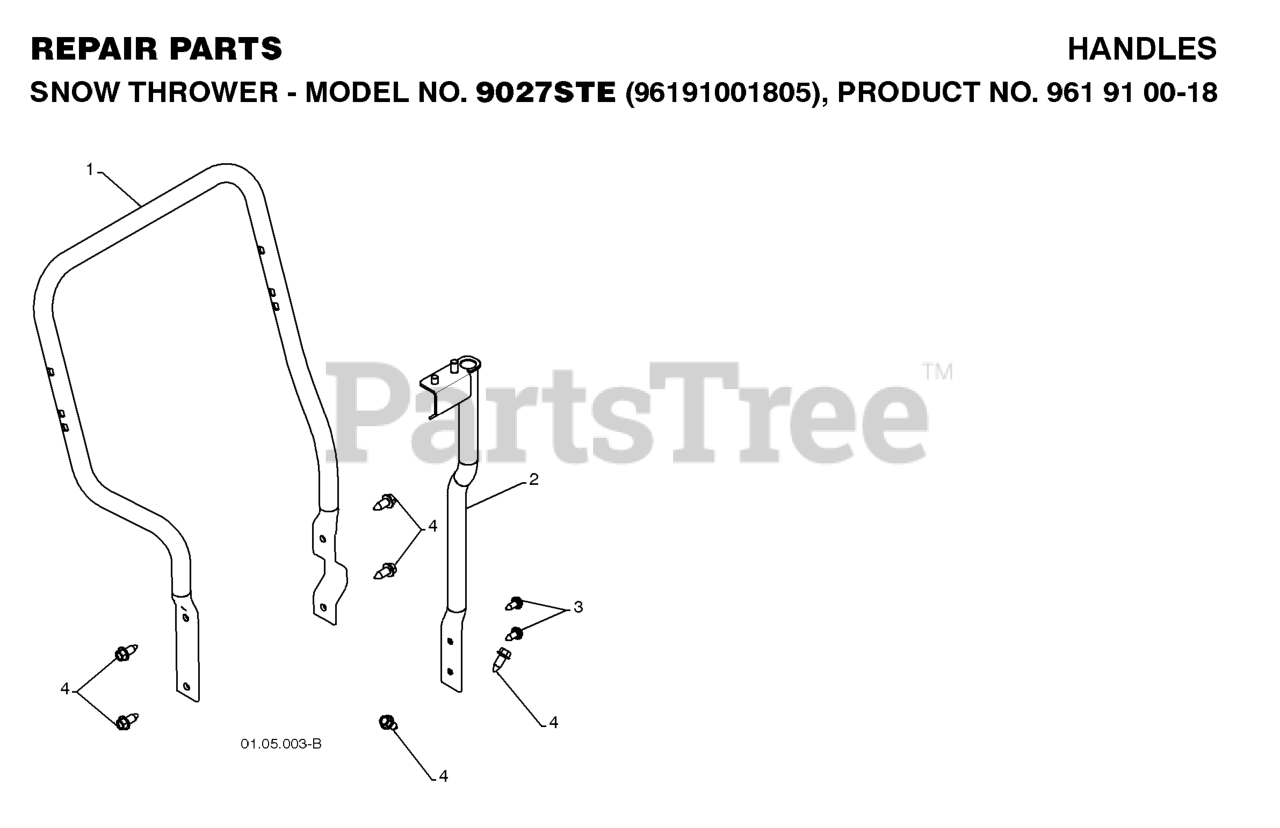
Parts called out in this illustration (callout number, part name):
1	TUBE.LOWER.HANDLE.SNOW.BLACK
2	SUPPORT.WELDMENT.ROTATOR.
3	SELF-TAPPING SCREW 5/16-18X3/4
4	SCREW 3/8-16X1
